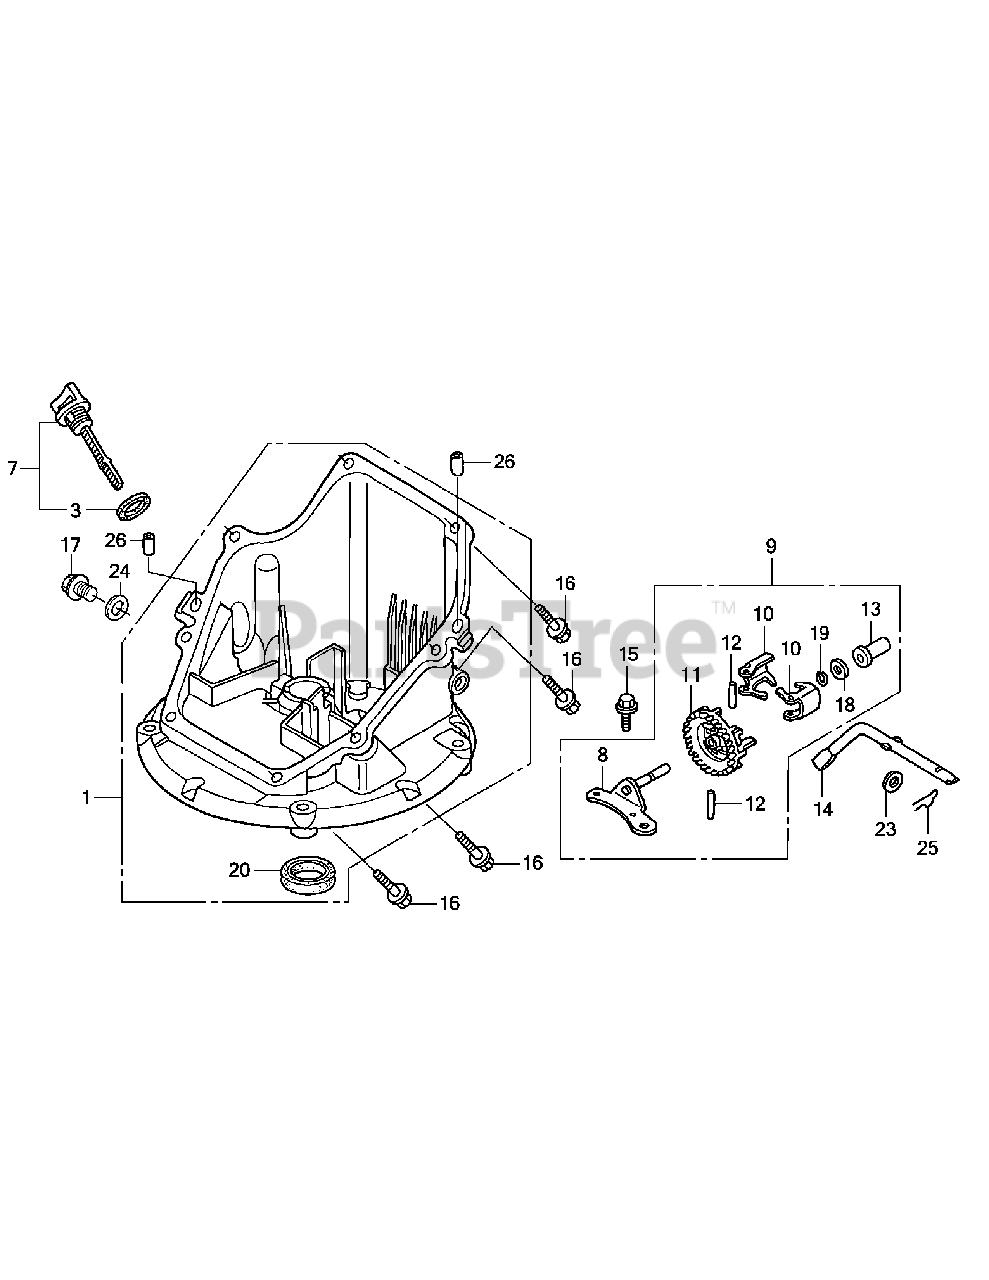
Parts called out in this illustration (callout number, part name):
1	Pan Assy., Oil (Sae)
3	Gasket, Oil Filler Cap
7	Gauge Assy., Oil Level
8	Pri; Shaft, Governor Holder
9	Pri; Governor Assy.
10	Weight, Governor
11	Holder, Governor Weight
12	Pin, Governor Weight
13	Slider, Governor
14	Shaft, Governor Arm
15	Bolt, Flange (6x14) (Ct200)
16	Bolt, Flange (6x25) (Ct200)
17	Sup; Bolt, Drain Plug (12x15)
17	Pri; Bolt, Drain Plug
18	Washer, Thrust (6mm)
19	Pri; Clip, Governor Holder
20	Oil Seal (28x41.25x6)
23	Washer, Plain (6mm)
24	Washer, Drain Plug (12mm)
25	Pin, Lock (8mm)
26	Pin, Dowel (8x20)
